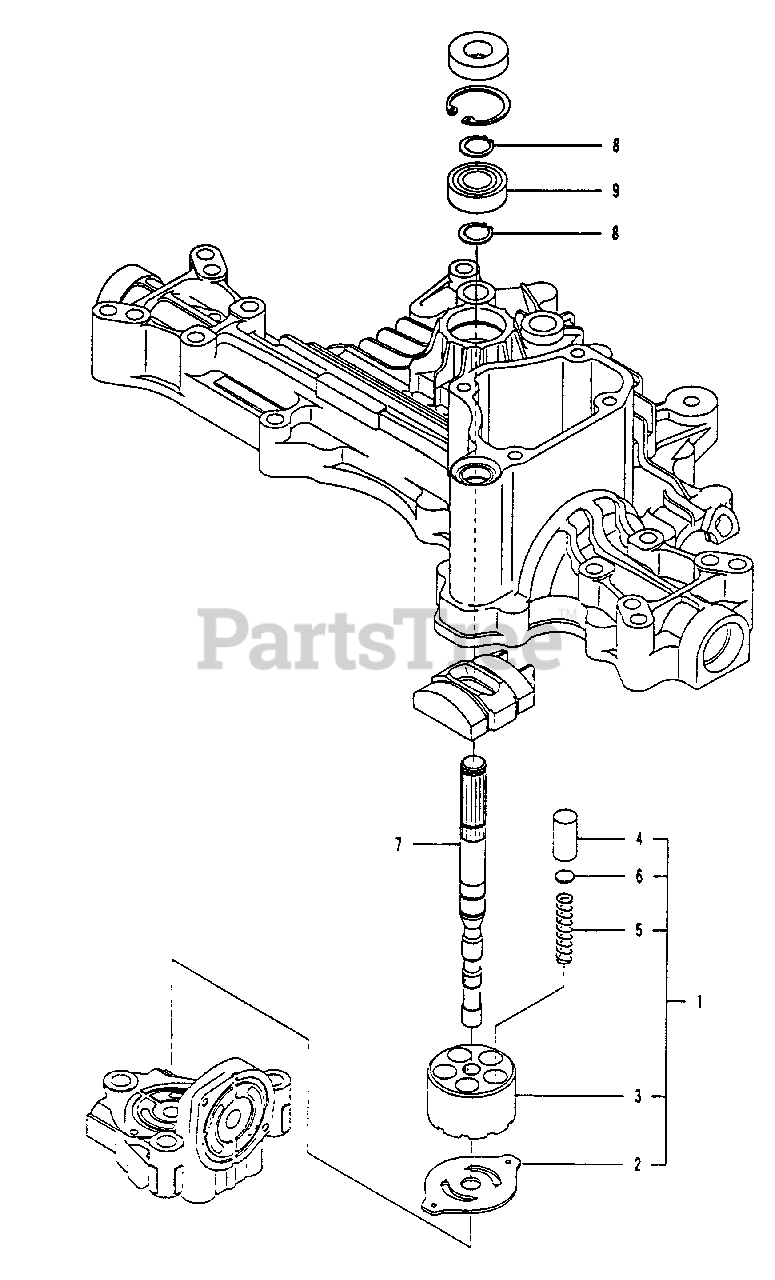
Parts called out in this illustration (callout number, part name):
1	CYLINDER BLOCK P CMP.
2	PLATE(PUMP
3	CYLINDER BLOCK
4	PISTON
5	SPRING (PISTON
6	WASHER 9, 4
9	BALL BEARING 6202C3
